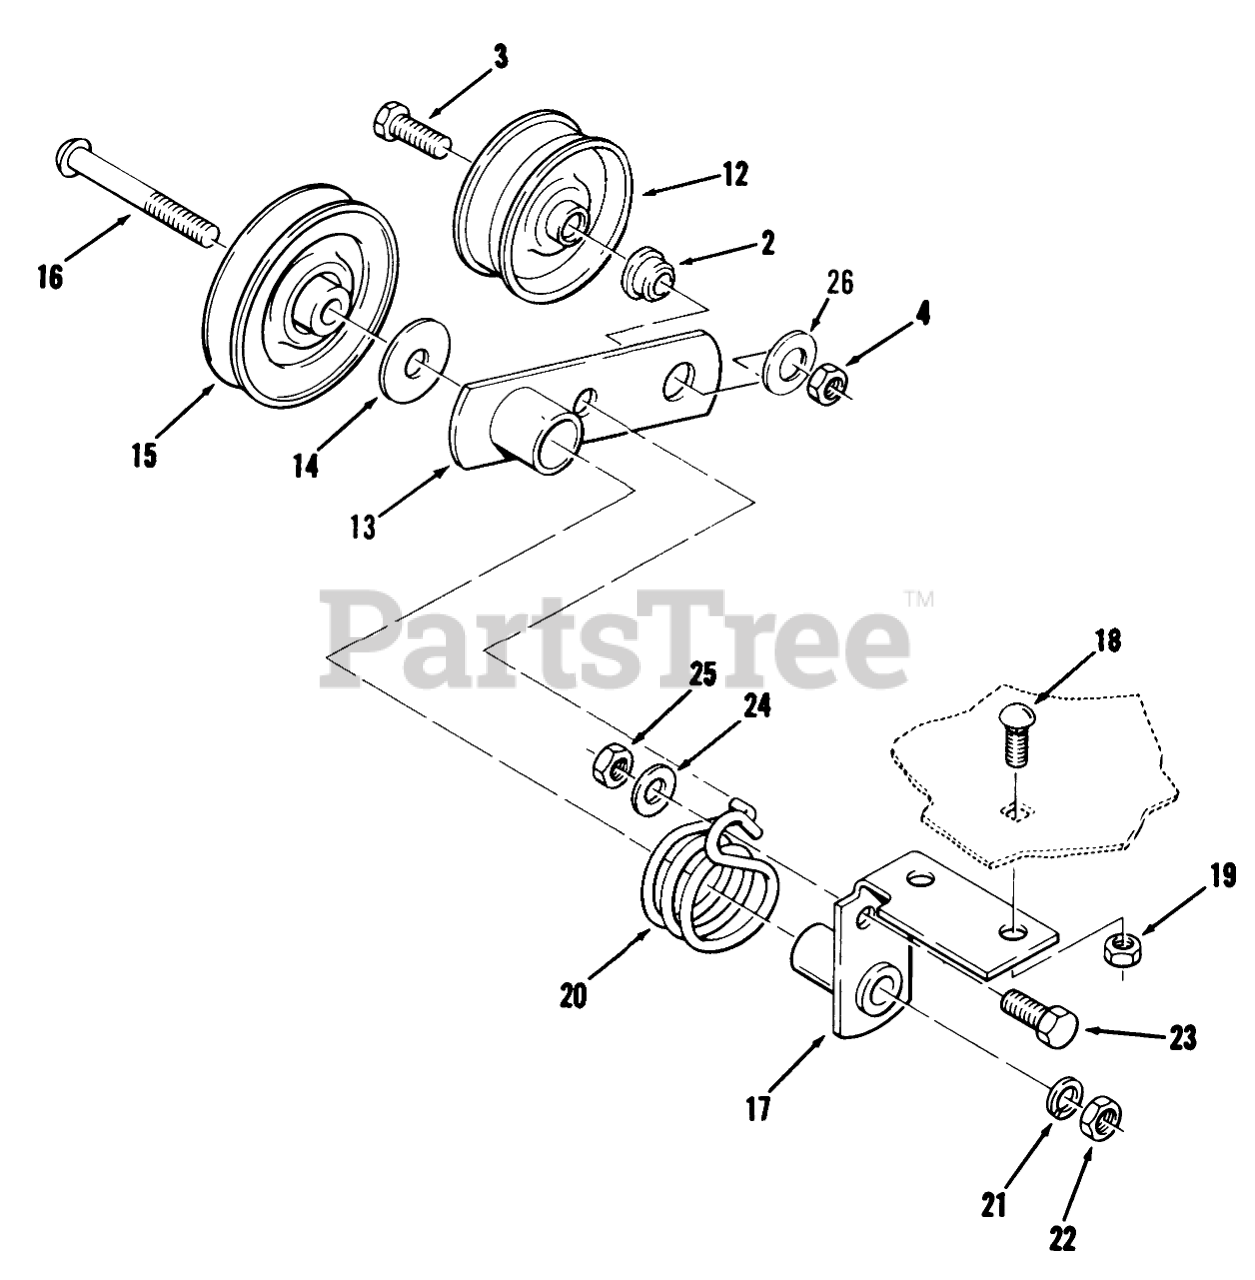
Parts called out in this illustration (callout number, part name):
2	SPACER-BRAKE LINK
3	Bolt
4	NUT
12	IDLER PULLEY
13	ASSY-IDLER ARM
14	WASHER
15	PULLEY-IDLER
16	SCREW 3/8-16X23/4
17	Idler Arm Support
18	Bolt
19	Nut
20	SPRING-TORSION
21	LOCKWASHER
22	Nut
23	Bolt
24	Washer
25	Nut
26	WASHER
